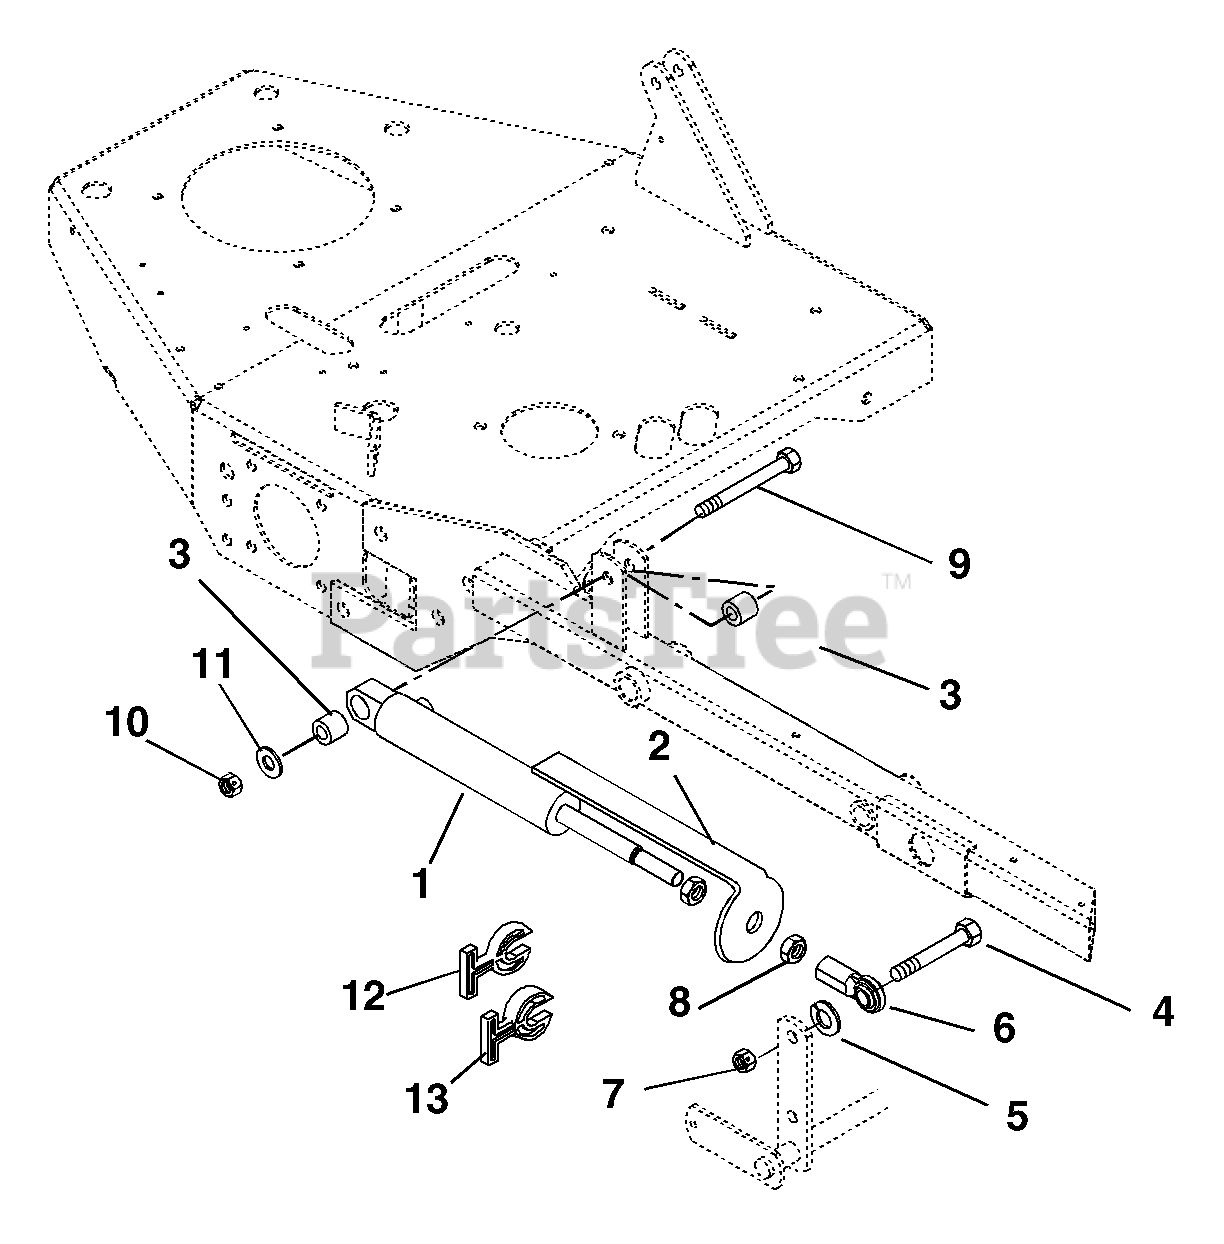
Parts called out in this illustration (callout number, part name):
1	Cylinder-Hydraulic Lift
2	Strap-Height of Cut Indicator
3	Bushing .516 x 1.000 x 1.05
4	Bolt-Hex .62-11 x 2.25 Grade 8
5	Washer-Lock .62 x .156
6	Rod End-Right Hand-Female .63
7	Nut-Locking-Center .62-11
8	Nut-Jam .63-18
9	Bolt-Hex .50-13 x 3.75 Grade 5
10	Nut-Locking-Center .50-13
11	Washer-Flat-Steel .515 x 1.625 x .25
12	Stop, Cylinder .34 Thick
13	Stop, Cylinder .68 Thick
